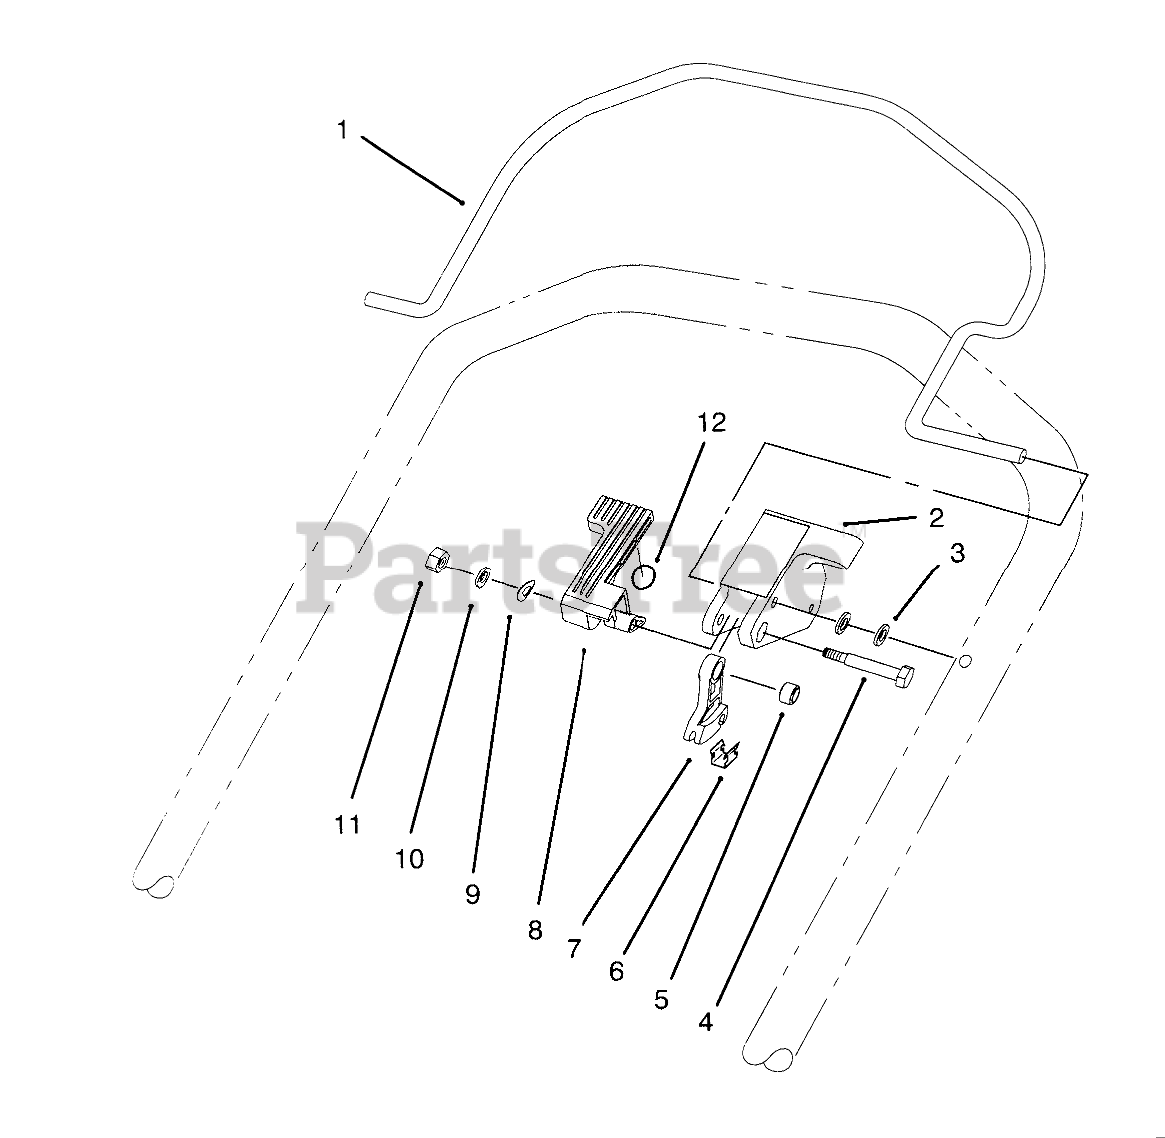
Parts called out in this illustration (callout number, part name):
1	BAIL - CONTROL
2	STOP - PIVOT, PLASTIC
3	WASHER-FLAT
4	SHOULDER BOLT
5	SPACER-LEVER, TRACTION
6	RETAINER - CABLE
7	LEVER-TRACTION
8	LEVER - SHIFT
9	WASHER - SPRING
10	WASHER-PLAIN
11	NUT-LOCK, NI
12	DECAL - TRACTION
